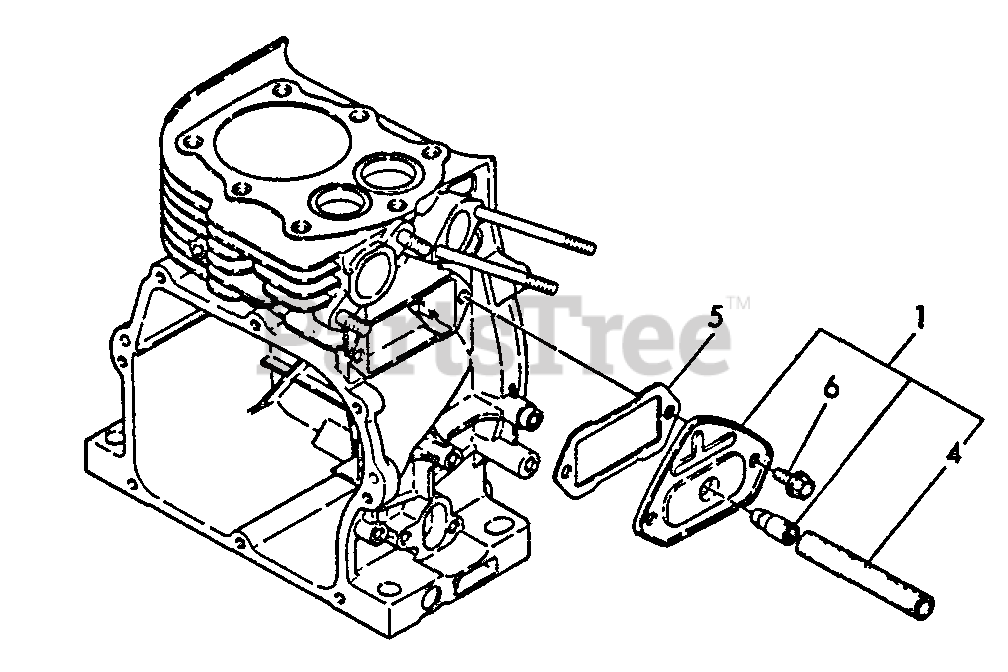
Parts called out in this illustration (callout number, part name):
1	BREATHER ASSY
4	PIPE, BREATHER
5	GASKET
6	BOLT - 6×8 -- PLATED
